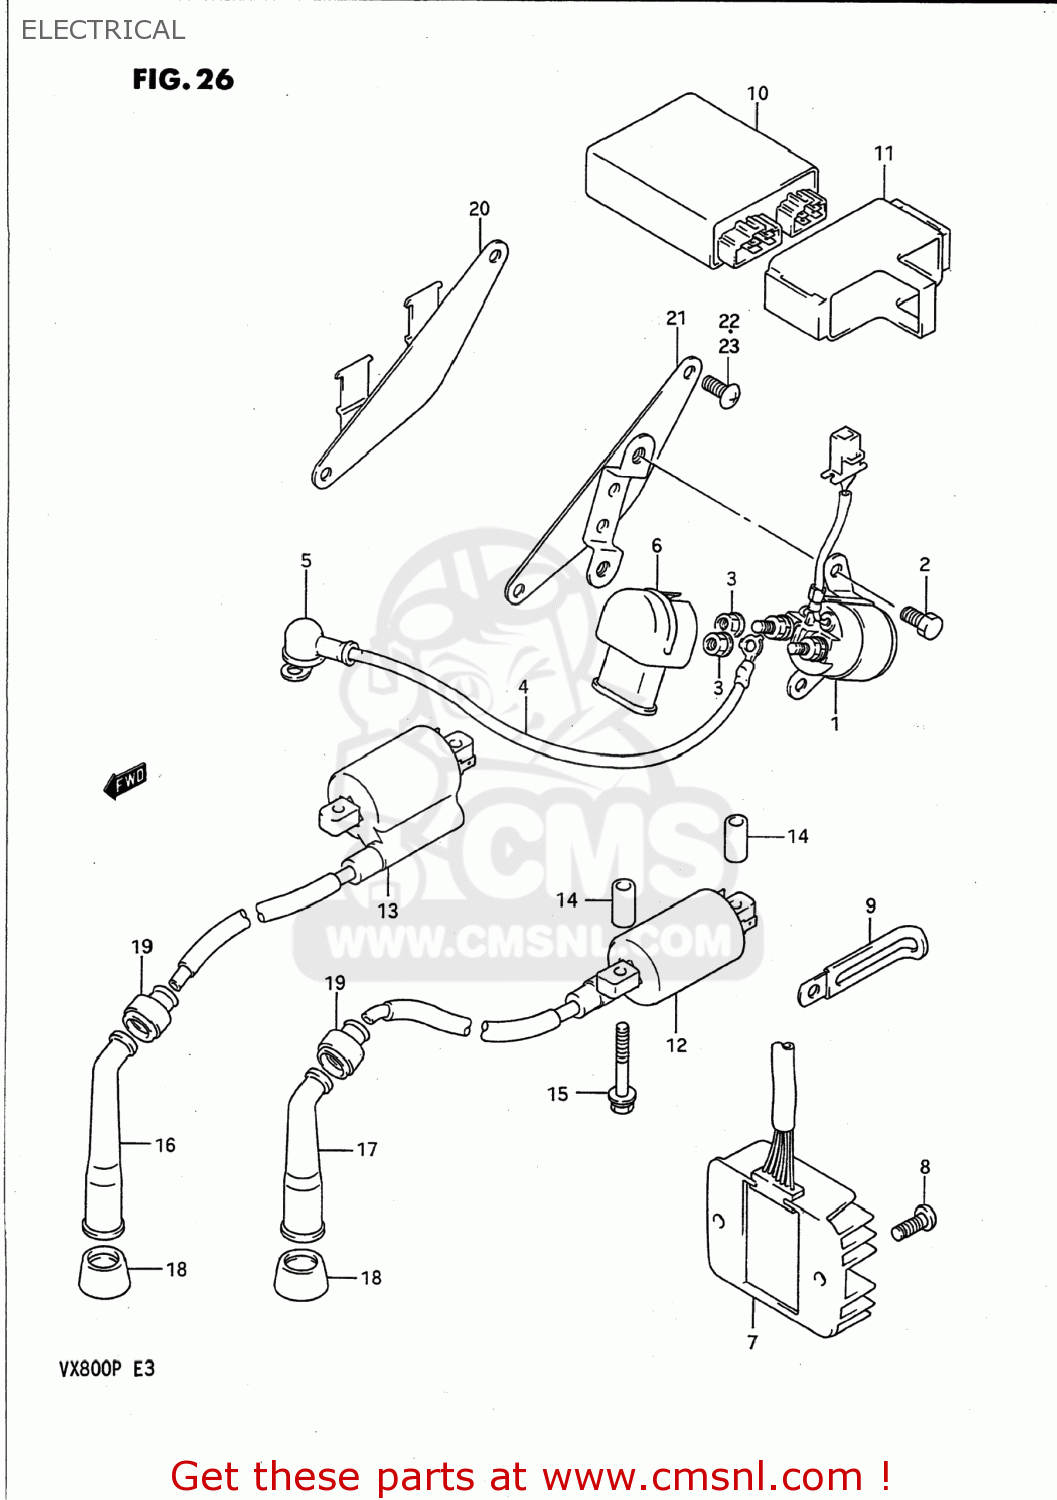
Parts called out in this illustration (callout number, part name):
1	RELAY ASSY,STARTING MOTOR
2	BOLT
3	NUT
4	WIRE,STARTER MOTOR LEAD
5	CAP,STARTER MOTOR TERMINAL
6	CAP,STARTER RELAY TERMINAL
7	RECTIFIER ASSEMBLY
8	SCREW
9	CLAMP
10	IGNITER
11	CUSHION,IGNITER
12	COIL ASSEMBLY,IGNITION
13	COIL ASSEMBLY,IGNITION,FRONT
14	SPACER(6.4X10X19)
15	BOLT
16	CAP,SPARK PLUG
17	CAP ASSY,SPARK PLUG
18	SEAL,SPARK PLUG CAP
19	SEAL,HIGH TENSION CORD
20	HOLDER COMP,ELECTRONIC PARTS
21	HOLDER COMP,ELECTRONIC PARTS
22	SCREW 6X12
23	SCREW
